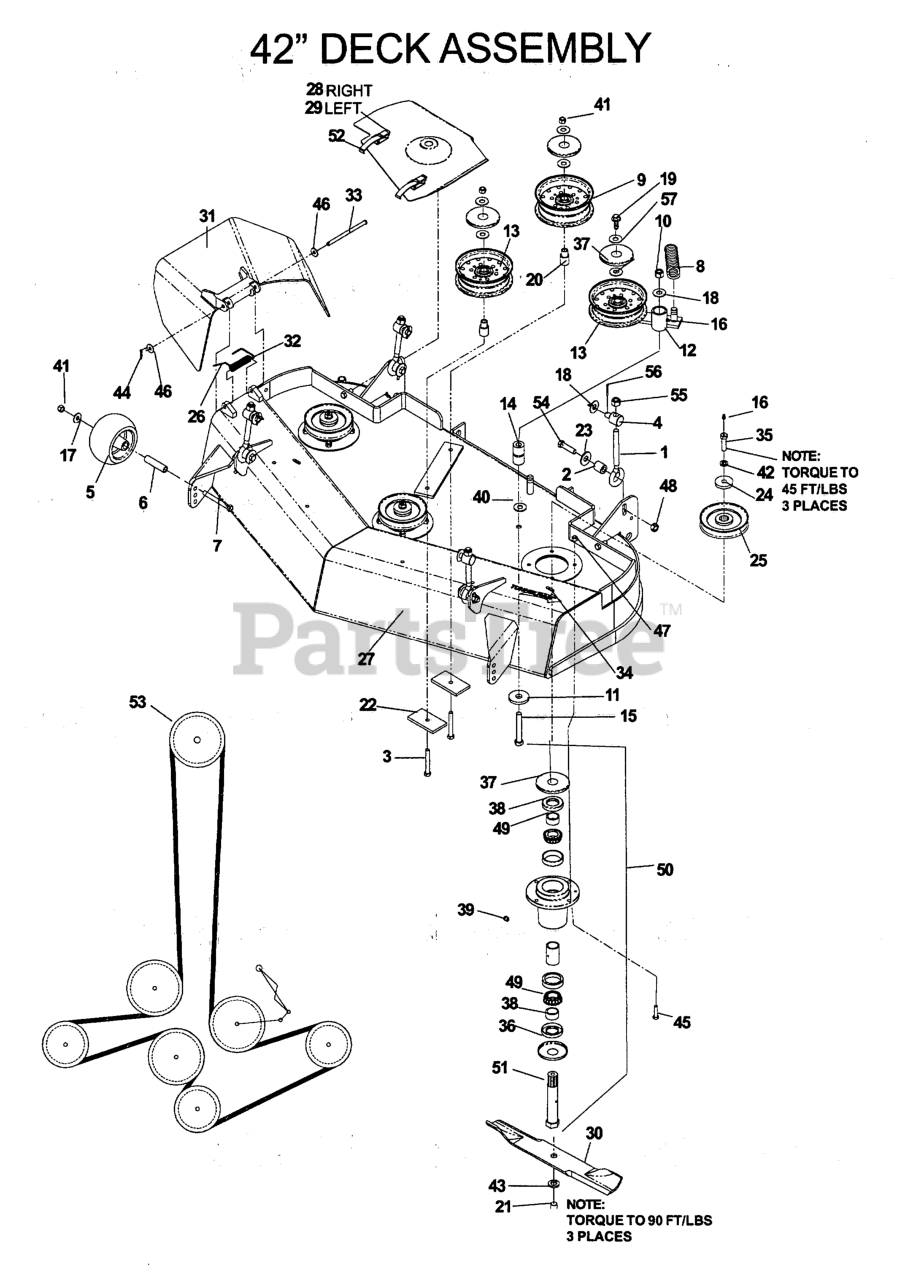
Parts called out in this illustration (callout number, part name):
3	SCREW 3/8C X 2 3/4 HEX CAP
5	ANTI-SCALP ROLLER
7	HCS 3/8C X 3 1/2
9	IDLER PULLEY (TALL)
10	NUT 1/2-13 HEX NYLOC ZD
11	WASHER, SUPPORT
13	IDLER PULLEY
14	PIVOT BUSHING
15	HCS 1/2C X 3 1/4
16	ZERK
17	WASHER 3/8 FLAT
18	WASHER 1/2 FLAT
19	4CS 3/8C X 1 SERRATED HEAD
20	IDLER BUSHING
21	HCS 5/8F X 1 1/4
22	SUPPORT PLATE
23	SPRING WASHER - .50
24	SPINDLE WASHER
25	RP PULLEY - 42/48"
26	CAP-SLEEVE
27	DECK W/DECALS 42"
28	BELT SHIELD ASM RH
29	BELT SHIELD ASM LH
30	BLADE 14-5/8" TUNNEL RAM
31	DISCHARGE CHUTE 42"
32	SPRING - TORSION
33	PIN-CLEVIS 5/16 DIA X 5.19 ZD
34	DECAL, TUNNEL RAM 4"
35	HCS 7/16-20 GD 8 SPEC
36	BOTTOM DUST CAP
37	TOP DUST CAP
38	SHAFT SEAL
39	PLUG-VENTED
40	WASHER 1/2 X 1.44 HRD ZD
41	NUT 3/8-16 NYLOC
42	WASHER 7/16 LOCK
43	LOCKWASHER 5/8
44	RP_COTTER PIN 1/8 X 3/4
45	HCS 5/16C X 1 1/4
46	WASHER 5/16 FLAT
47	NUT 5/16 NYLOC
48	NUT 7/16C CENTERLOCK
50	SPINDLE ASSY - 52/61"
51	MINI SPINDLE
52	DRAW LATCH
53	DECK BELT
54	HCS 7/16 - 14 X 1 3/4
55	NUT 1/2-13 HEX NYLOC ZD
56	PIN COTTER 1/8 X 1 ZD
57	WASHER, 3/8 SPEC
